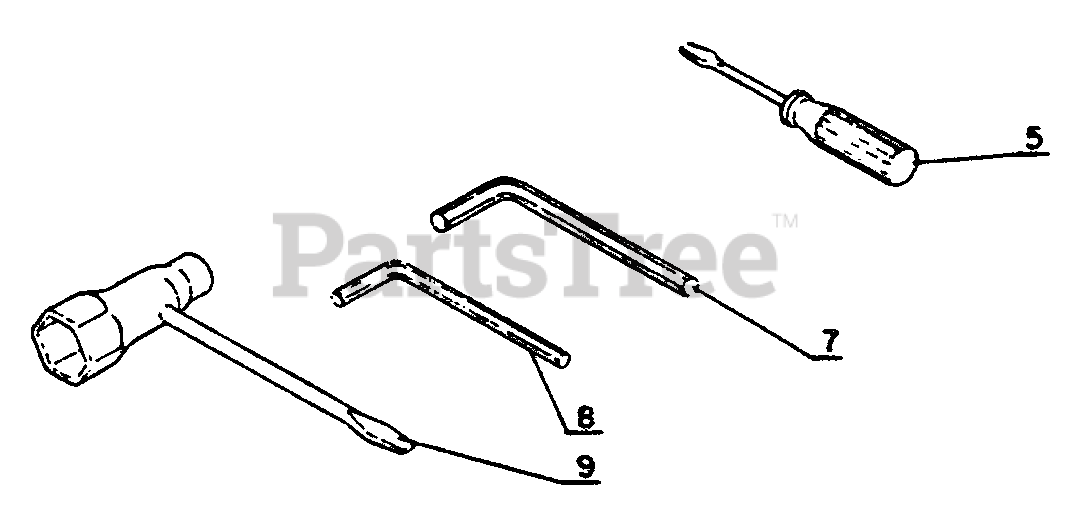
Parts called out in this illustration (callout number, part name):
5	SCREWDRIVER
7	HEX KEY - 4mm
8	HEX KEY - 3mm
9	T-WRENCH - 10X19mm
